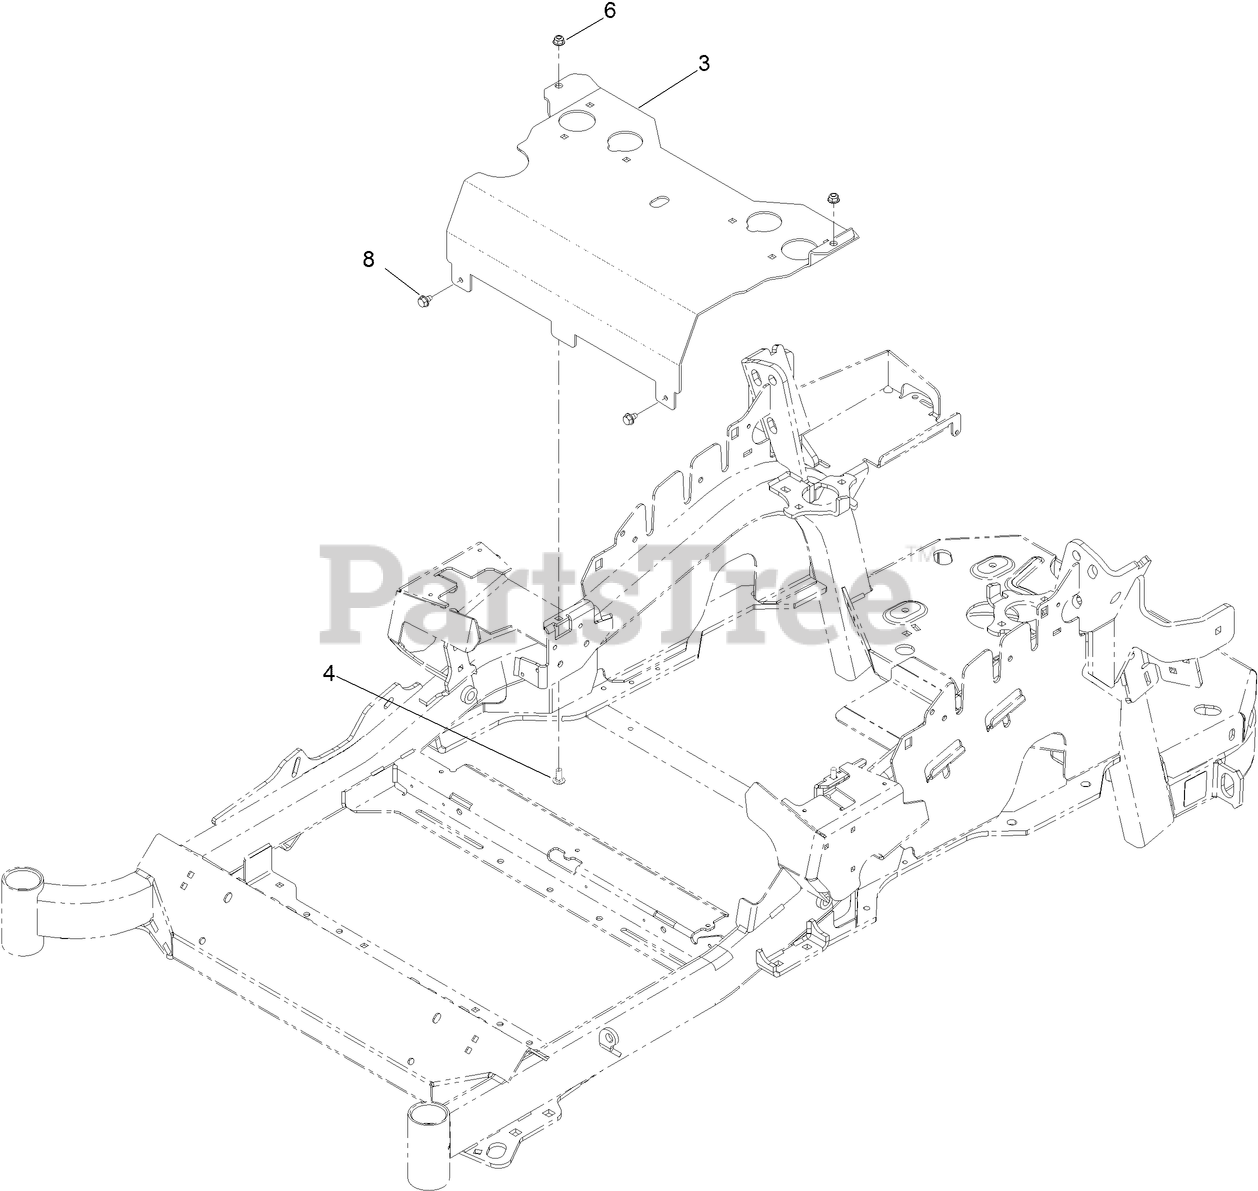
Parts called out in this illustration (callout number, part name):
3	PANEL-FRONT, SEAT MOUNT
4	SCREW-CARR
6	NUT-HF, NI
8	SCREW
